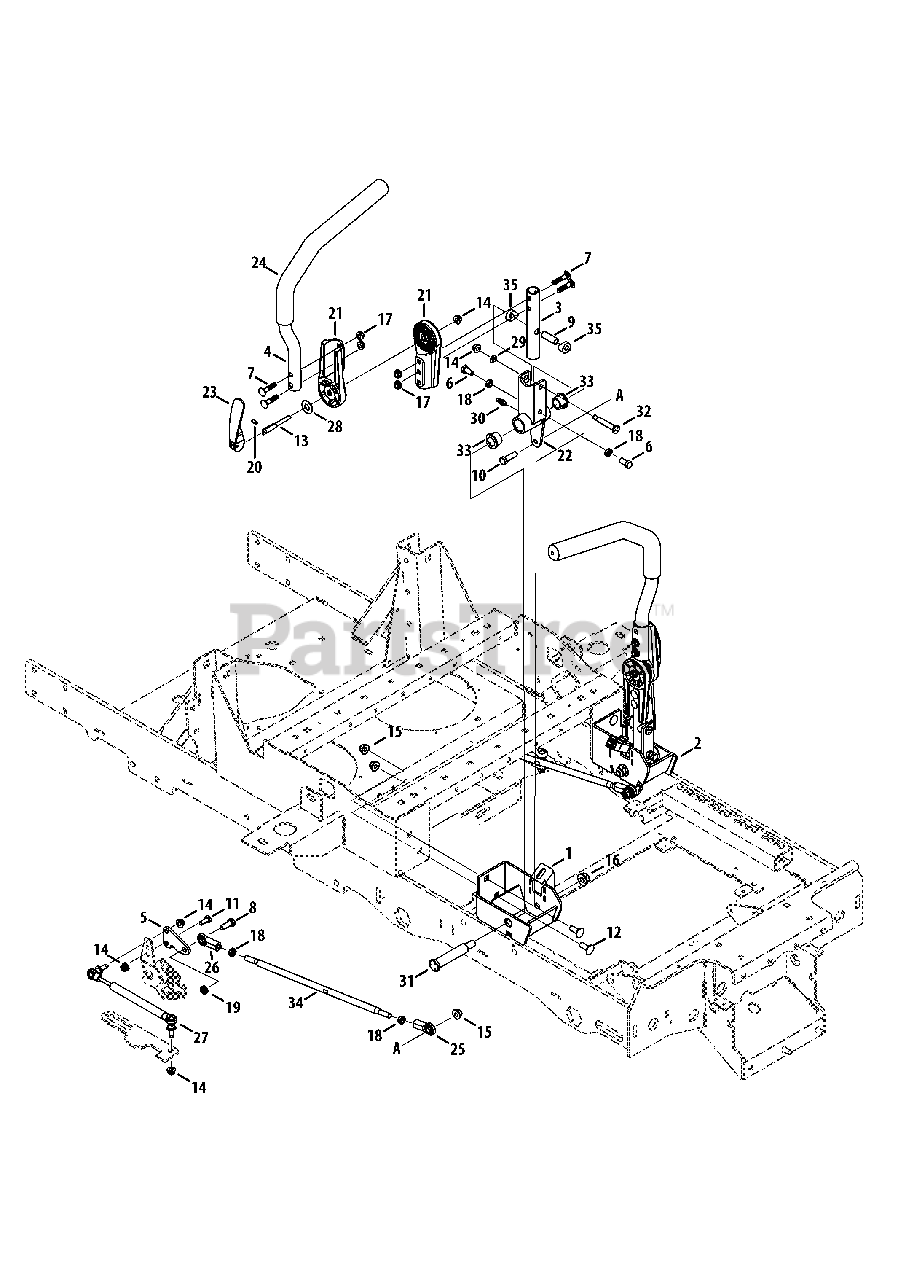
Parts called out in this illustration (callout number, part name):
1	Pivot Housing Weldment, RH
2	Pivot Housing Weldment, LH
3	Lower Pivot Tube Weldment
4	Lapbar Tube Weldment
5	Return to Neutral Control Bracket
6	Hex Cap Screw, 3/8-24 x .750
7	Carriage Bolt, 5/16-18 x 1.50
8	Hex Cap Screw, 3/8-16 x 1.00
9	Spacer, .385 x .5000 x 1.40
10	Hex Cap Screw, 3/8-16 x 1.25
11	Hex Cap Screw, 5/16-18 x .75
12	Carriage Bolt, 3/8-16 x 1.00
13	Bolt, 5/16-18 x 2.73
14	Nut, 5/16-18, Flangelock
15	Nut, 3/8-16, Flnagelock
16	Nut, 1/2-13, Flangelock
17	Nut, 5/16-18, Centerlock
18	Jam Nut, 3/8-24
19	Jam Nut, 3/8-16
20	Heavy Duty Spring Pin
21	Handle Adjustment
22	Pivot Control
23	Pivot Cam Lever
24	Grip, 1.0 ID
25	Ball Joint, 3/8-24
26	Ball Joint, 3/8-24, LH
27	Damper Control Cylinder
28	Bevel Washer, .525 x 1.00 x .050
29	Washer, .330 x .630 x .064
30	Grease Fitting, 1/4-28
31	Shoulder Bolt, .75 x 3.25, 1/2-13
32	Shoulder Screw, .375 x 1.813, 5/16-18
33	Bearing, .75 x 1.00 x .73
34	Control Rod
35	Spacer, .500 x .875 x .250
